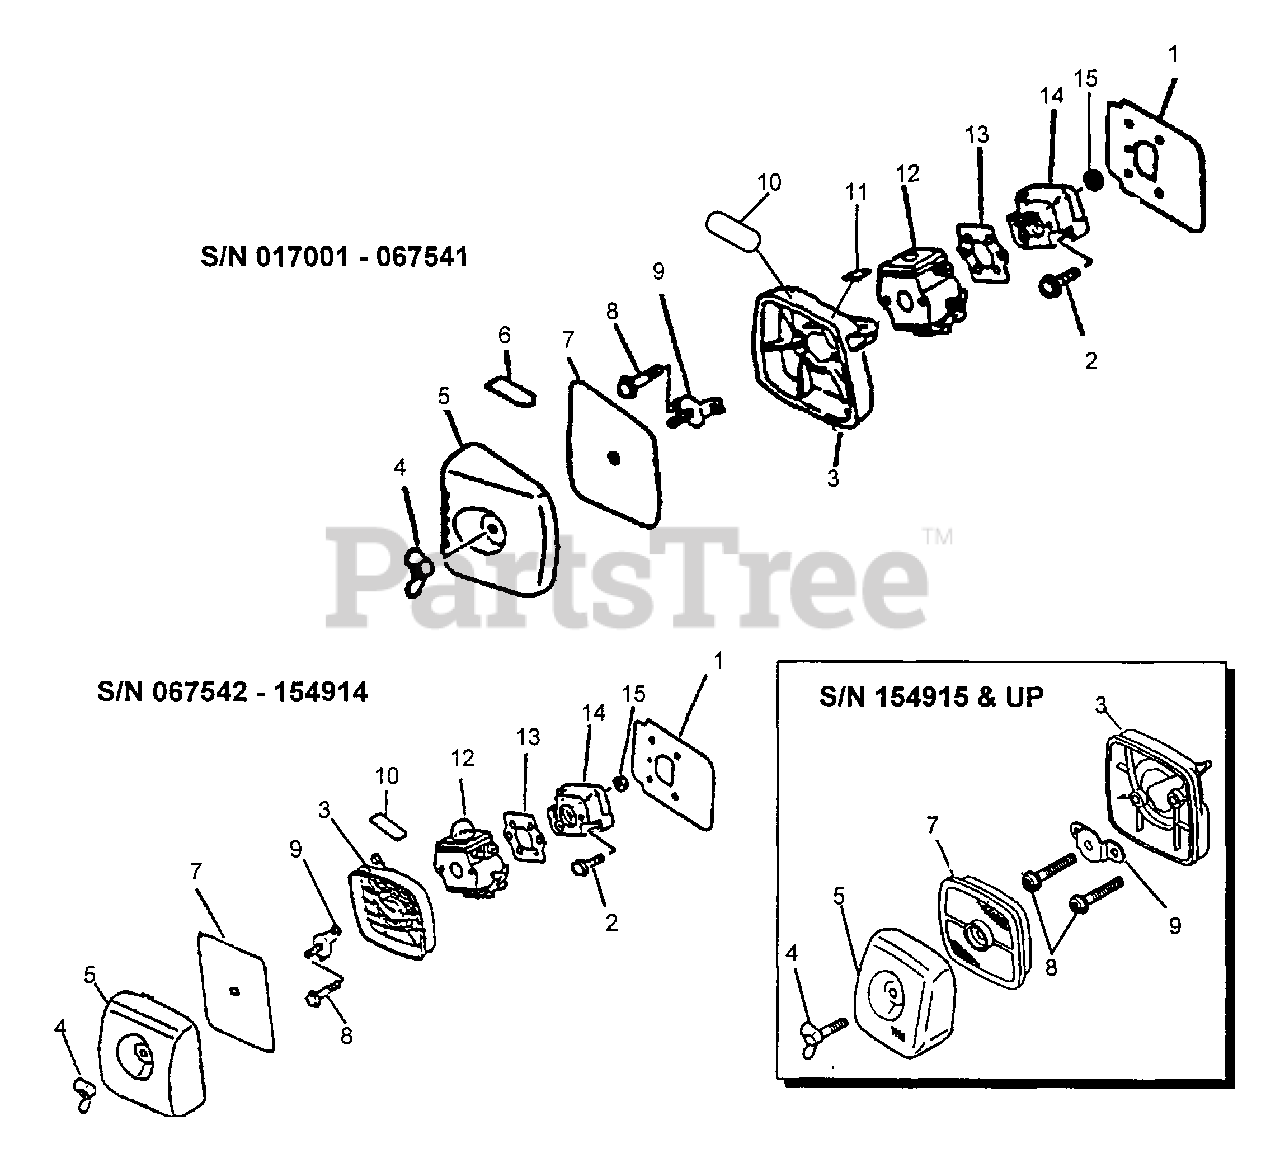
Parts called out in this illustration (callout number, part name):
1	HEAT SHIELD, INTAKE
2	SCREW 5×20
3	AIR FILTER CASE ASSY
4	WINGNUT - 6
4	BOLT, WING 5×20
5	COVER, AIR FILTER
5	COVER, AIR FILTER - GRAY
6	LABEL - TOP
7	FILTER, AIR
7	FILTER, AIR - SINGLE LAYER
8	SCREW 5×64
8	SCREW 5×65
9	PLATE, PREVENT
10	LABEL, CHOKE
10	LABEL - CHOKE
11	LABEL - IDLE
12	CARBURETOR - C1U-K10
12	CARBURETOR - C1U-K17
12	CARBURETOR - C1U-K27B
12	CARBURETOR - C1U-K45
13	GASKET, INTAKE
14	INSULATOR, INTAKE
15	NUT M5
